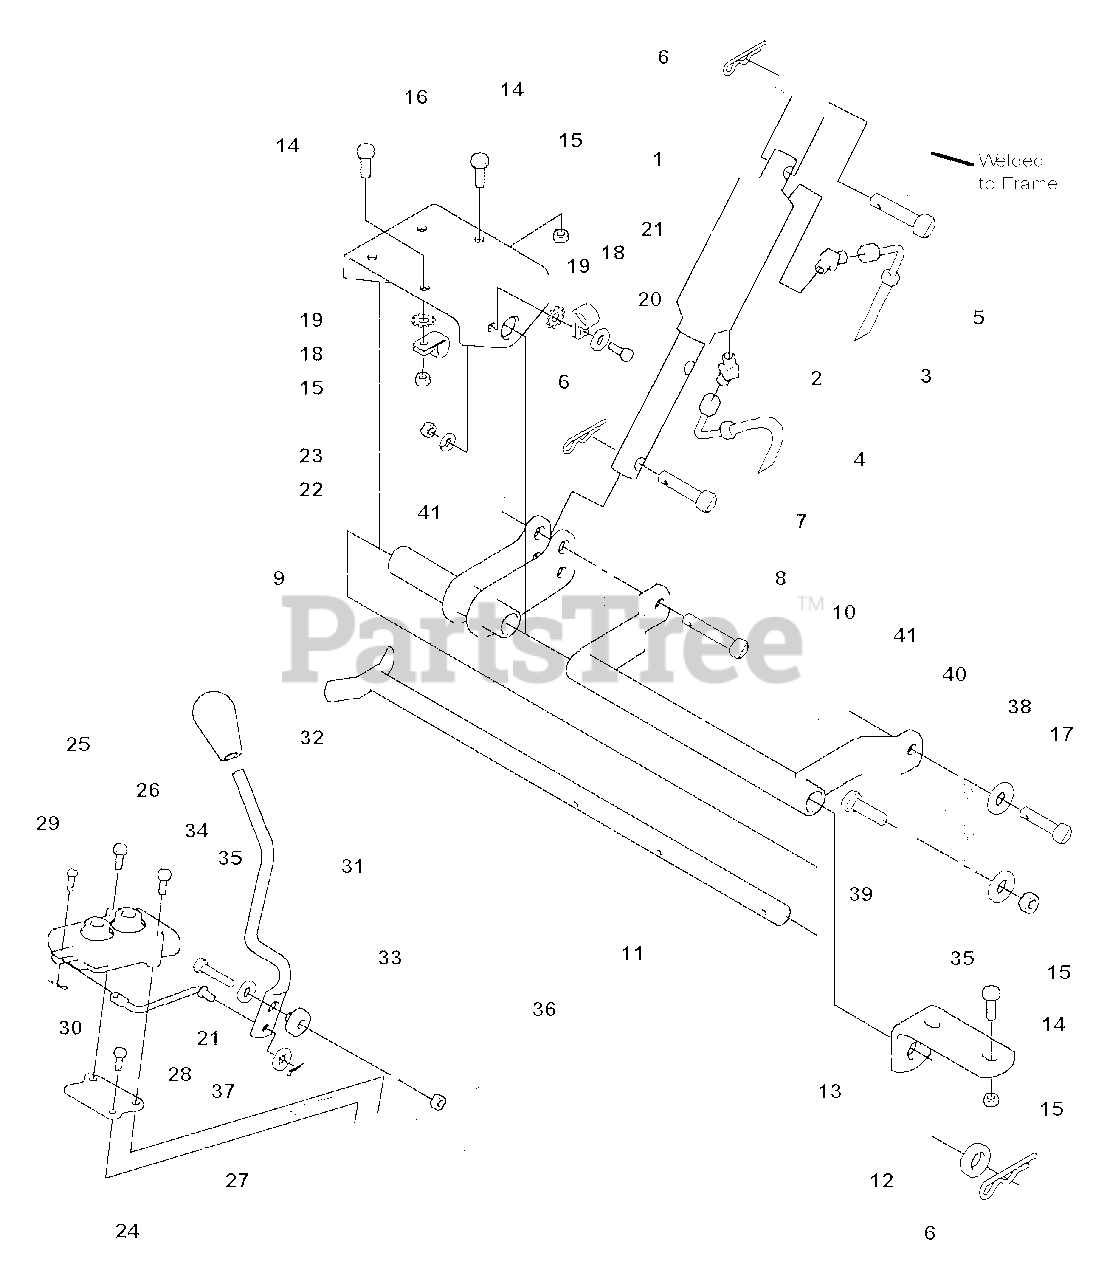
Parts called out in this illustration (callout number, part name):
1	CYLINDER, Hydraulic Lift (Includes Ref. No. 5)
2	FITTING, Hydraulic, 45 Degree Elbow, 1/8NPT x 1/2-20
3	HYDRAULIC LINE, Long, Valve A -- Cylinder Piston
4	HYDRAULIC LINE, Short, Valve B -- Cylinder Rod
5	PIN, Clevis
6	CLIP, Hairpin
7	PIN
9	LIFT ARM ASSEMBLY
10	LIFT TUBE ASSEMBLY
11	SHAFT ASSEMBLY
12	WASHER, Plain
13	LIFT, Pivot Bracket
14	CAPSCREW, Hex Head, 5/16-18 x 7/8
15	NUT, Hex Nylon Lock, 5/16-18
16	SUPPORT, Lift
18	CLAMP
19	WASHER, Lock, External Tooth, 5/16
20	CAPSCREW, Hex Head,1/4-20 x 1
21	WASHER, 1/4
22	WASHER, Lock, 1/4
23	NUT, Hex, 1/4-20
24	PLATE, Valve Mounting
25	VALVE, Lift
26	CAPSCREW, Hex Head, Taptite, 1/4-20 x 1-1/2
27	CAPSCREW, Hex Head, Taptite, 1/4-20 x 3/8
28	LINK, Lift Valve Spool
29	PIN
30	COTTER PIN, 1/16 x 3/4
31	LEVER, Hydraulic Lift
32	KNOB, Lift Lever
34	CAPSCREW, Hex Head, 5/16-18 x 1-1/4
35	WASHER, Flat, 5/16
36	NUT, Hex Head, Whiz Lock, 5/16-18
37	PIN, Cotter, 3/32 x 3/4
38	WASHER, Plain, 3/8
39	CAPSCREW, Hex Head, 5/16-18 x 1-1/2
40	CHAIN, 3 Link (used on 50" Mowers)
40	CHAIN, 4 Link (used on 44" Mowers)
41	PIN, Cotter Locking
